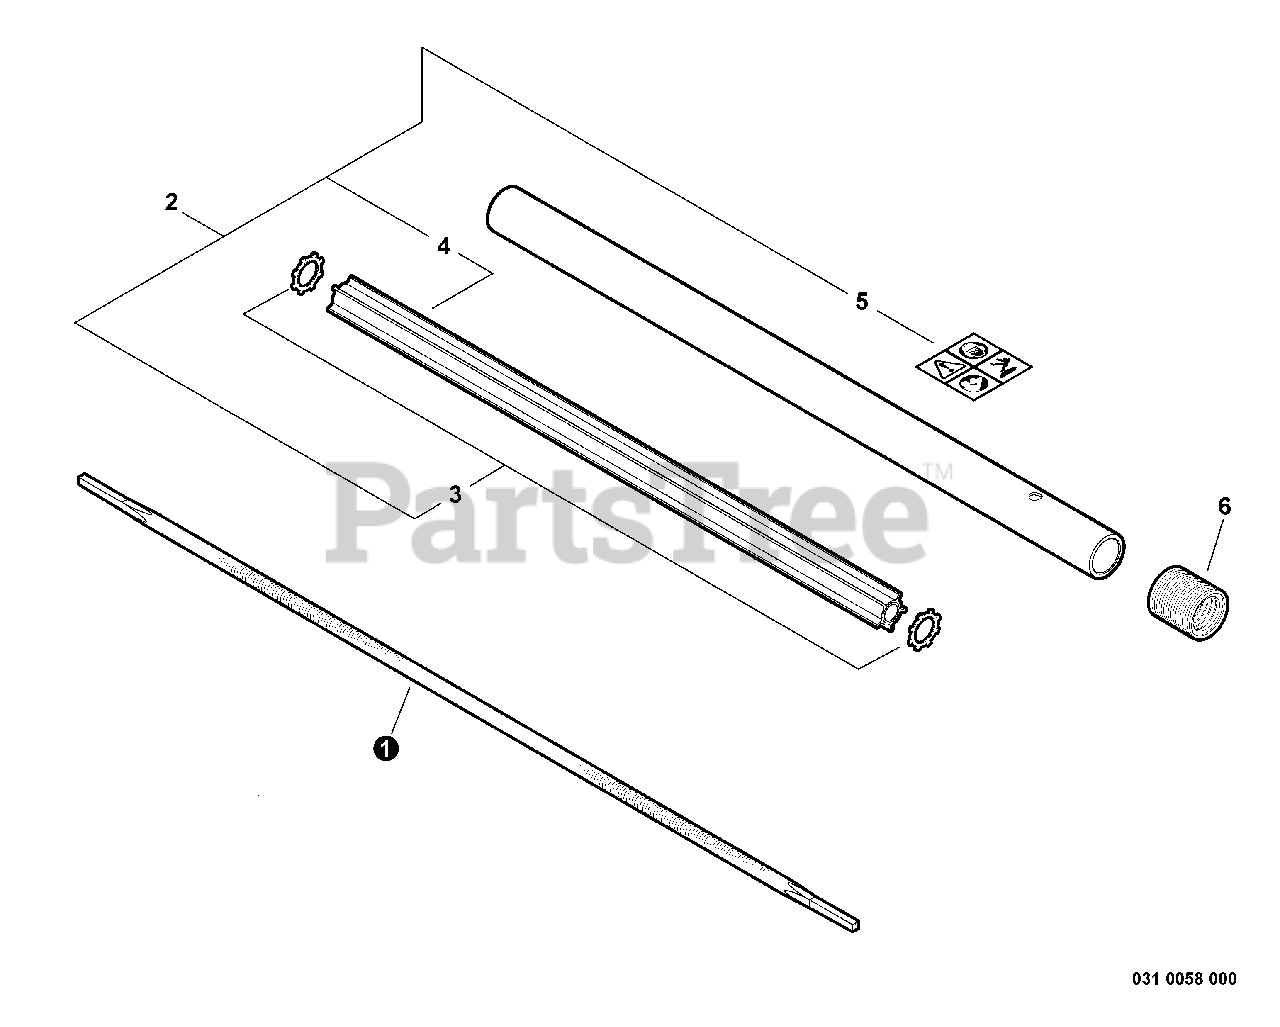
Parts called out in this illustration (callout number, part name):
1	DRIVESHAFT - FLEXIBLE
2	PIPE ASSY
5	LABEL - CAUTION
6	TUBE, PROTECTIVE - CORRUGATED
